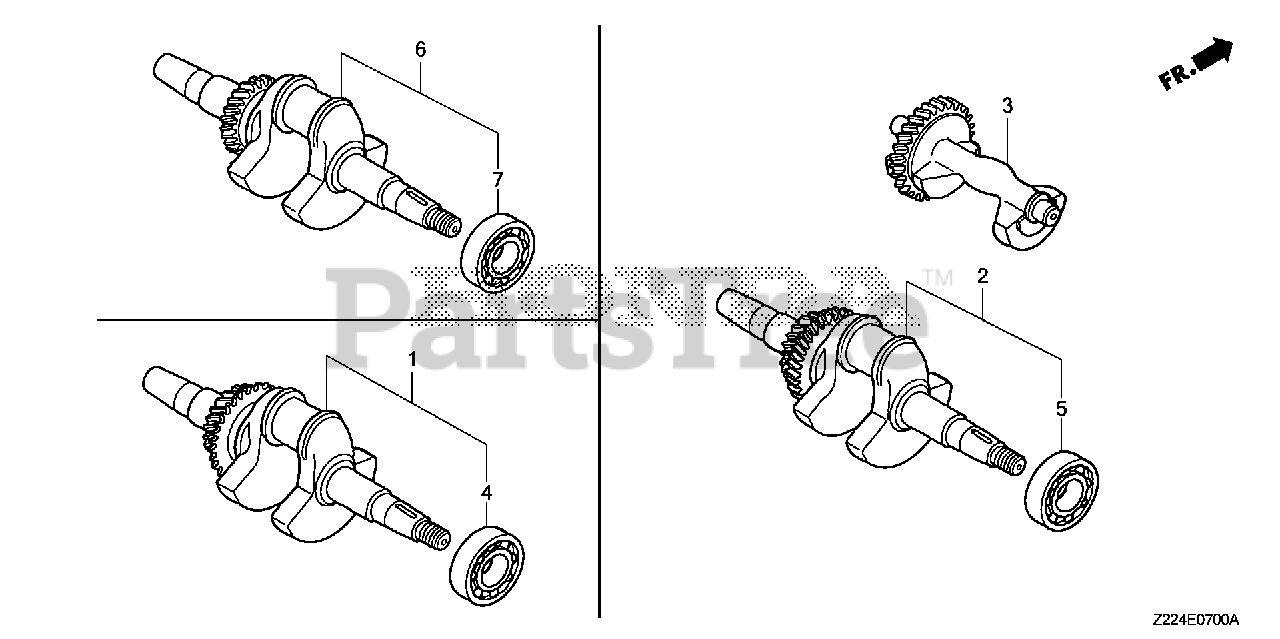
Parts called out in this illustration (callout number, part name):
2	CRANKSHAFT
3	WEIGHT, BALANCER
5	BEARING, RADIAL BALL (6207)
